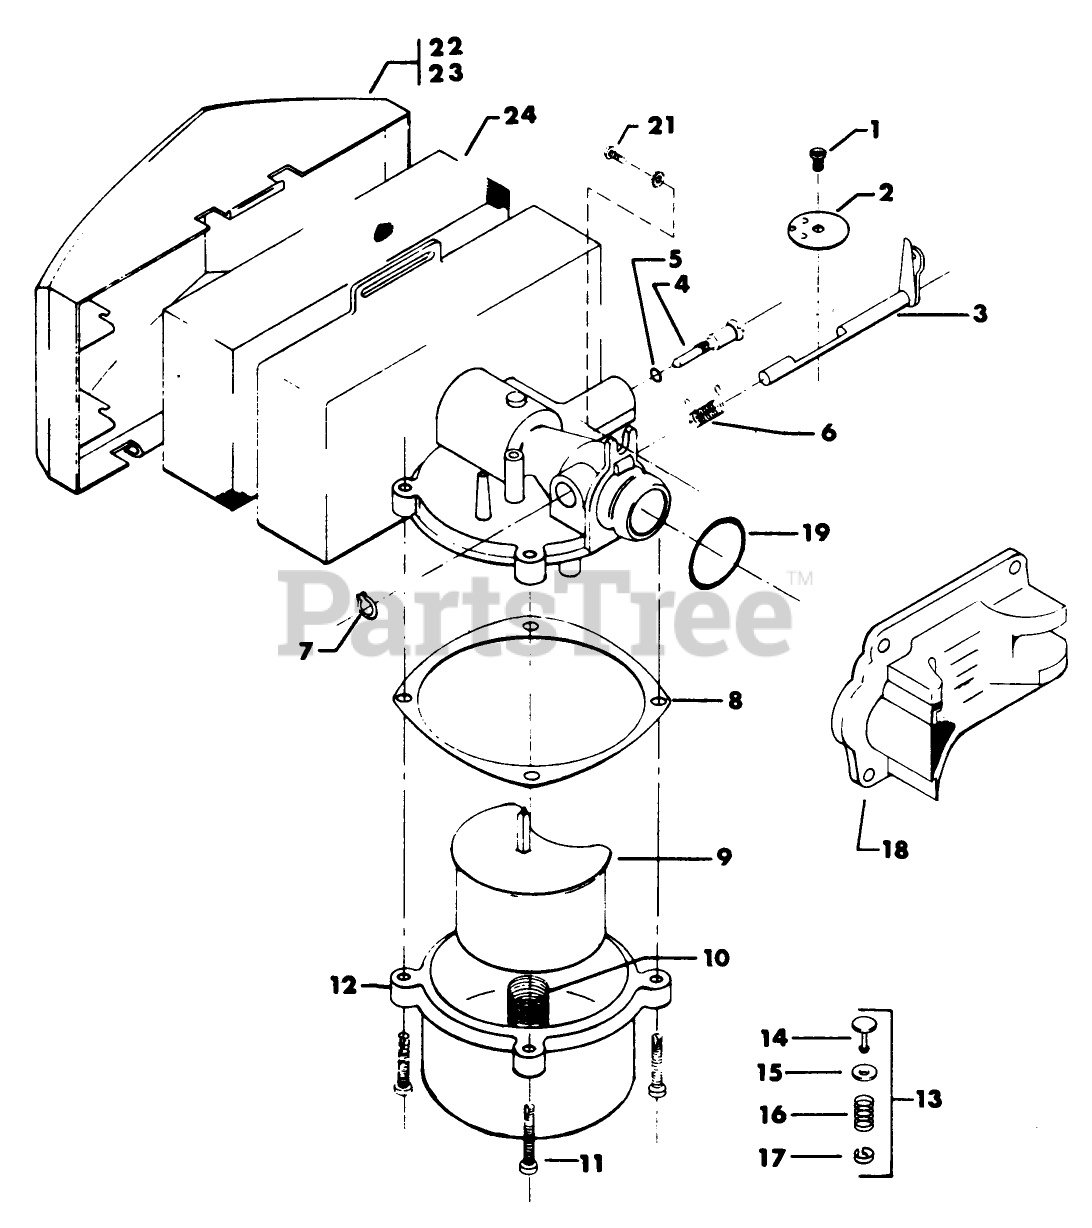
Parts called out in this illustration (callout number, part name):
1	Screw, disk
2	THROTTLE DISC S
3	THROTTLE LEVER S
4	SCREW CARB ADJ S
7	RING GRIP S
9	ORDER 681843 CARB
10	FLOAT SPRING
11	SCREW-HH
14	VALVE STEM S
15	VALVE SEAT S
17	VALVE KEEPER S
22	COVER FILTER
23	COVER FILTER S
24	AIR FILTER S
